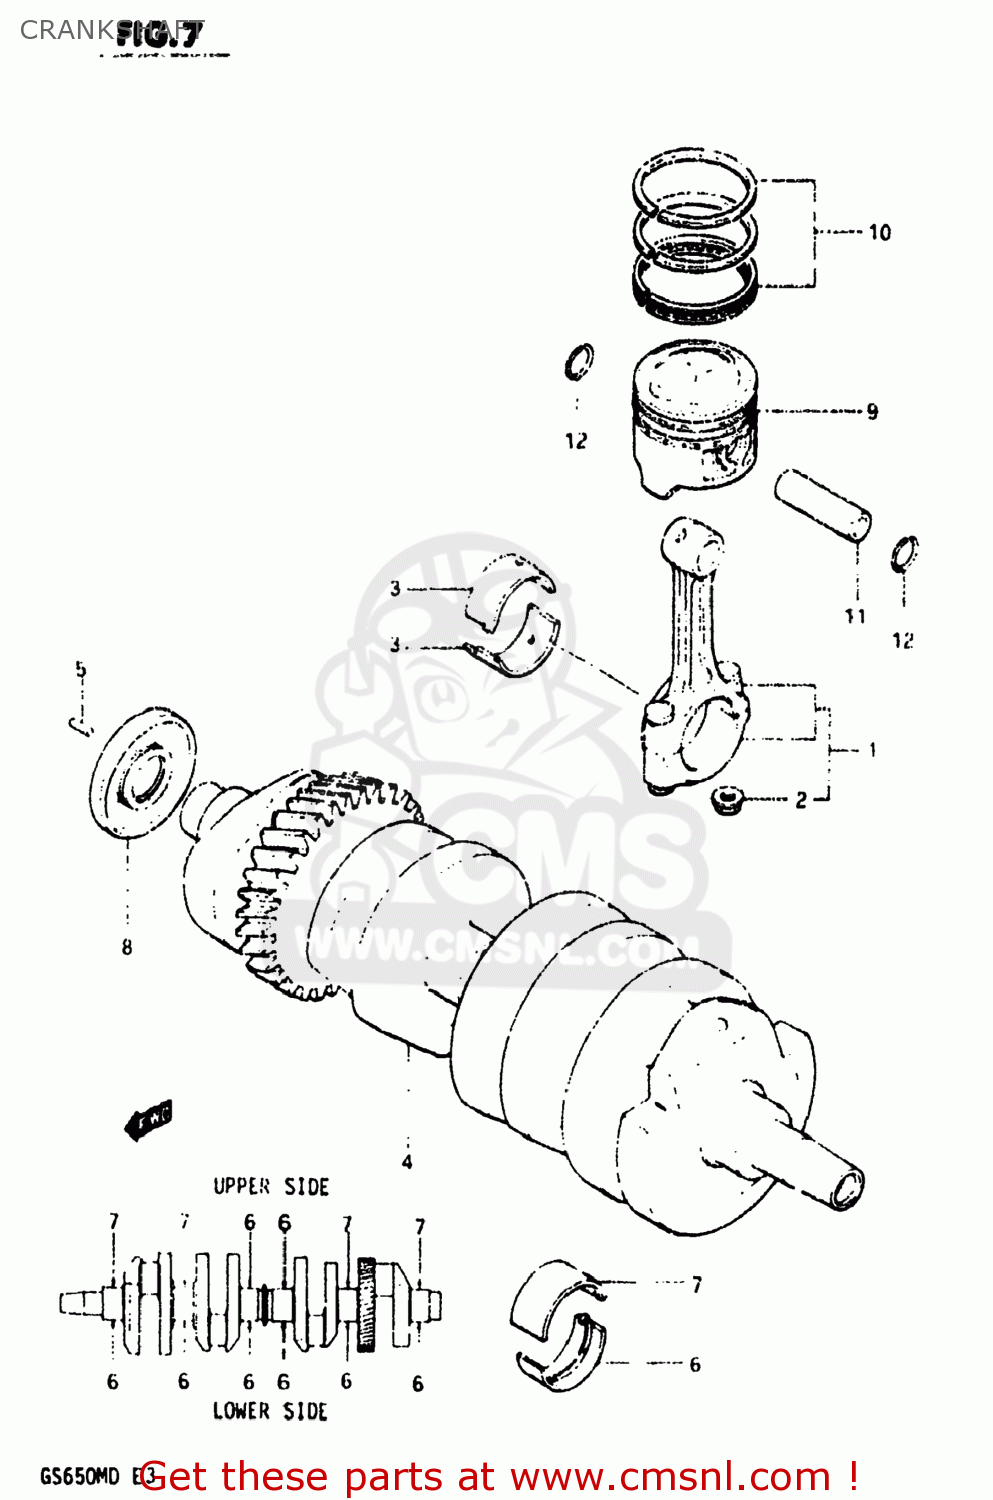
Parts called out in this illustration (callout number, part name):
1	ROD ASSEMBLY,CONNECTING
2	NUT
3	BEARING,CRANK PIN
4	CRANKSHAFT ASSEMBLY
5	PIN
6	METAL CRANKSHAFT
7	METAL CRANKSHAFT
8	OIL SEAL
9	PISTON (62.00MM)
10	RING SET,PISTON
11	PIN,PISTON
12	CIRCLIP
